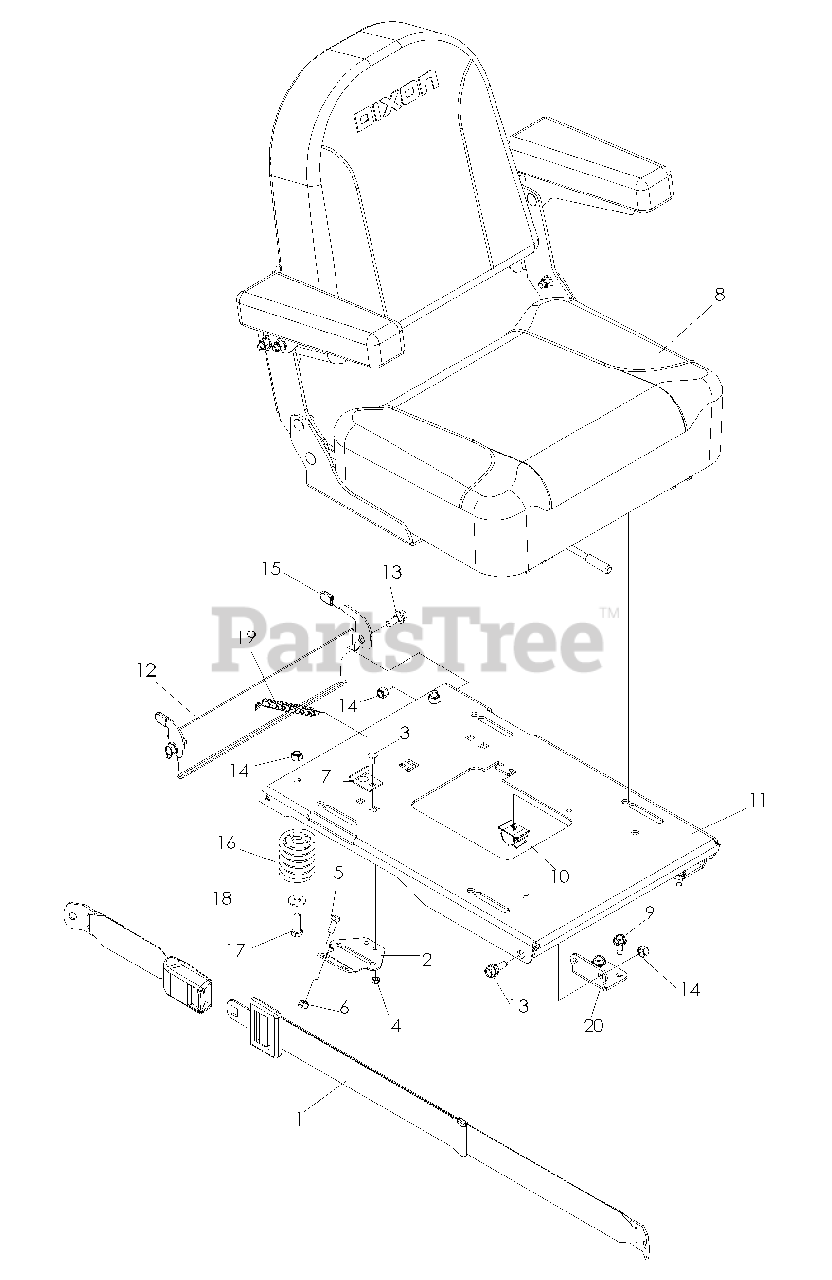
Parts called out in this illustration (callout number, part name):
1	SEAT BELT
2	MOUNT, SEAT BELT
3	RHSNB 5/16-18 X 3/4
4	NUT 5/16 NYLOC
5	HCS 7/16-14 X 1 GR 5 ZD
6	NUT 7/16C CENTERLOCK
7	STOP, SEAT - BLACK
8	SEAT ASM.
9	BOLT 5/16-18 X 3/4
10	PUSH-MOUNT WIRE CLIP
11	PAN, SEAT - BLACK
12	LATCH, SEAT - BLACK
13	SB 5/16-18 HEX HD GD5, BLK ZN
14	NUT 5/16 NYLOC
15	GRIP, VINYL, .09 X .495 X.75
16	SPRING, SEAT
17	HCS 5/16C X 1
18	WASHER 5/16 FLAT
20	PIVOT, SEAT PAN
